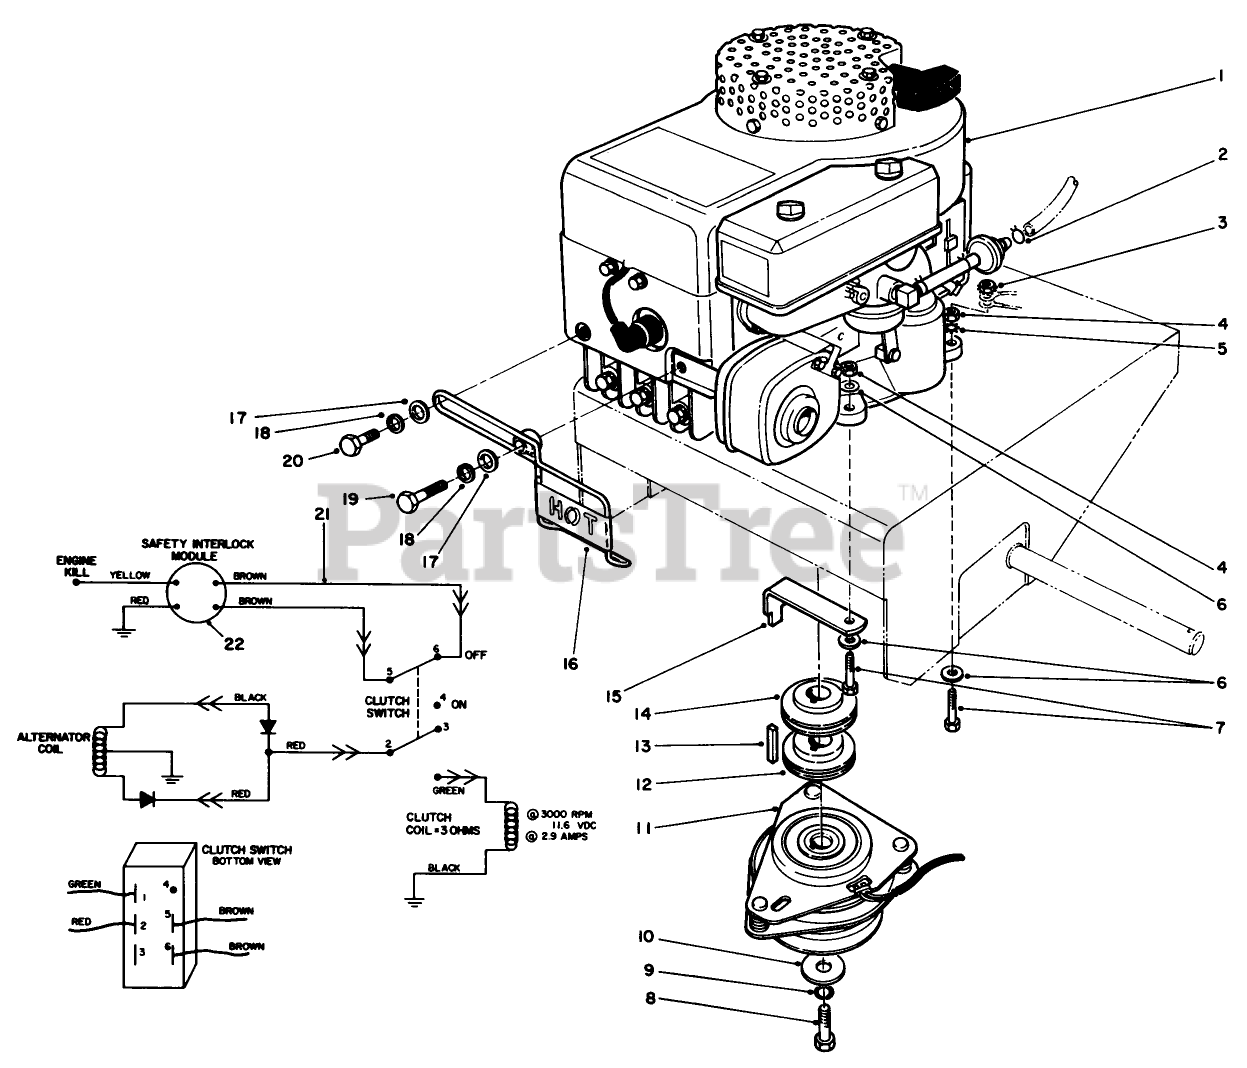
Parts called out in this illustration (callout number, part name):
1	Engine-12 H.P.
2	CLAMP-HOSE
3	NUT-KEPS
4	NUT-LOCK, CONE
5	WASHER-LOCK
6	WASHER-PLAIN
7	SCREW-HH
8	SCREW-HH
9	WASHER-LOCK
12	SHEAVE-HALF, LOWER
13	KEY-SQUARE
14	SHEAVE-HALF, UPPER
17	WASHER-FLAT
18	WASHER-LOCK
19	SCREW-HH
20	SCREW-HH
